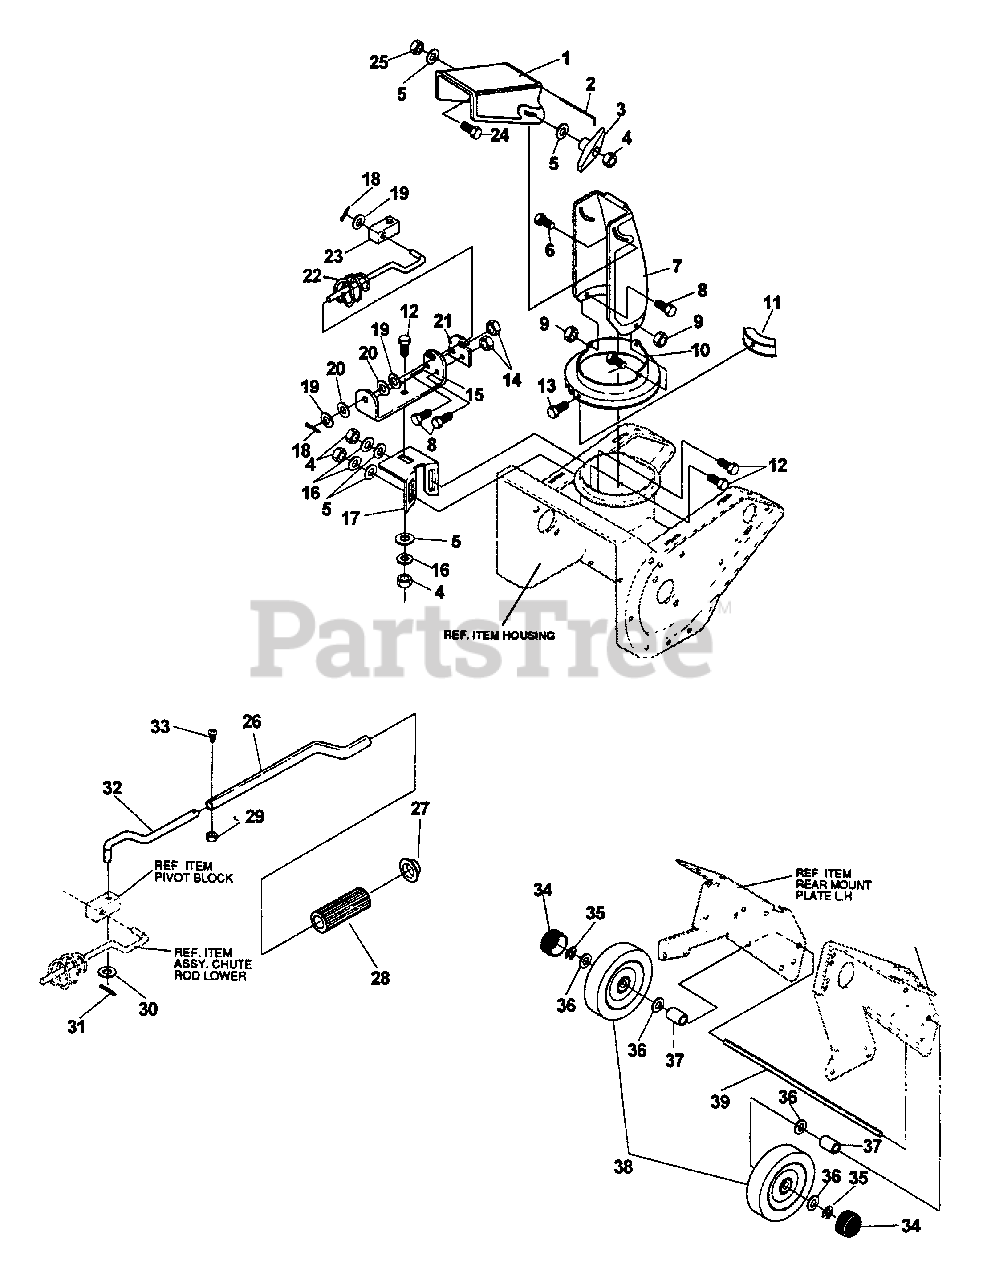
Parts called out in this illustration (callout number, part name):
1	CHUTE ASSY - UPPER
2	WIRE, HINGE 6.65 LONG SR
3	KNOB, T 2 BLADE W/5/16-18 NUT
4	NUT - 5/16-18
5	WASHER
6	BOLT - 5/16-18 X 1.25"
7	CHUTE - LOWER
8	SCREW - 1/4-20 X .50"
9	LOCKNUT - 1/4-20
10	RING, LOWER CHUTE
11	CLIP, CHUTE RING PLASTIC
12	BOLT - 5/16-18 X 3/4"
13	SCREW - 1/4-14 X 5/8"
14	NUT - 1/4-20
15	BRACKET, CHUTE ROD
16	LOCKWASHER
17	BRACKET, WORM ADJUST
18	PIN, SPLIT
19	WASHER - .40 X .75 X .025"
20	WASHER - WAVE
21	PLATE, CHUTE ROD
22	CHUTE CONTROL ROD ASSY - LOWER
23	BLOCK, PIVOT PLASTIC
24	SCREW - 5/16-18 X 3/4"
25	NUT - 5/16-18
26	ROD, UPPER CHUTE CONTROL
27	NUT - PUSH -- 3/8
28	KNOB, CHUTE, CRANK
29	LOCKNUT - 10-32
30	WASHER - .40 X .75 X .025"
31	PIN, SPLIT
32	ROD, CHUTE CONTROL MIDDLE
33	SCREW - 10-32 X 7/8"
34	HUB CAP 3/20
35	RING, RETAINING
36	WASHER
37	SPACER, SLEV .407X.63X.440
38	WHEEL ASSY
39	SHAFT, AXLE 5/21
